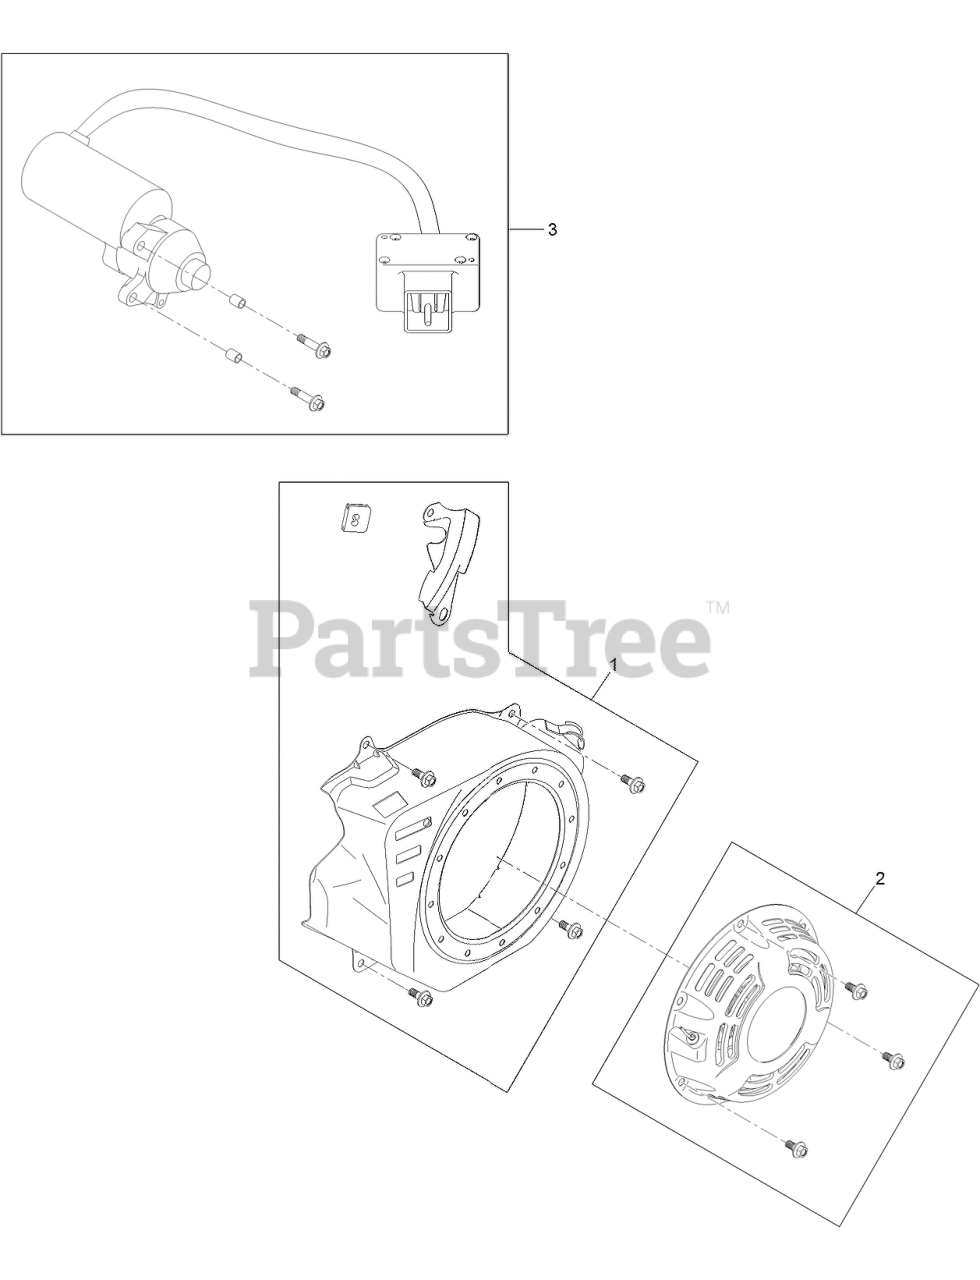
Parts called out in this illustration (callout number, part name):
1	BLOWER SHROUD KIT
2	RECOIL KIT
3	ELECTRIC STARTER KIT
